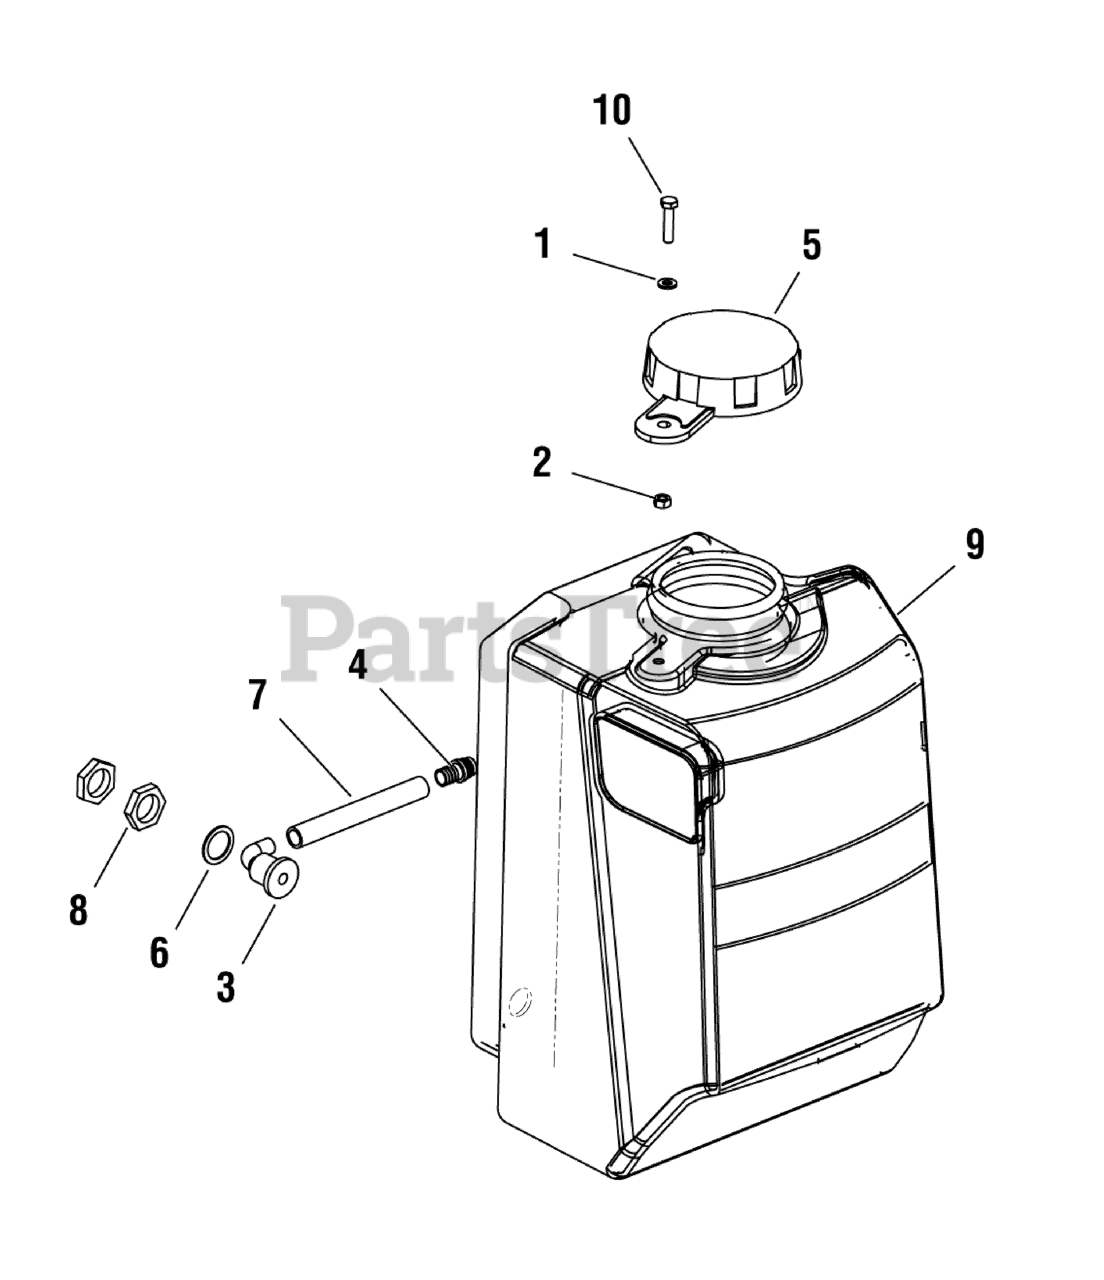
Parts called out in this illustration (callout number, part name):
1	WASHER, Flat, 8
2	NUT, Hex, M8
3	PIPE JOINT
4	QUICK CONNECTOR, Male Joint
5	COVER, Water Tank
6	WASHER, Asbestos
7	WATER PIPE
8	BOLT, Hex, M24
9	WATER TANK
10	BOLT, Hex, M8 x 35
